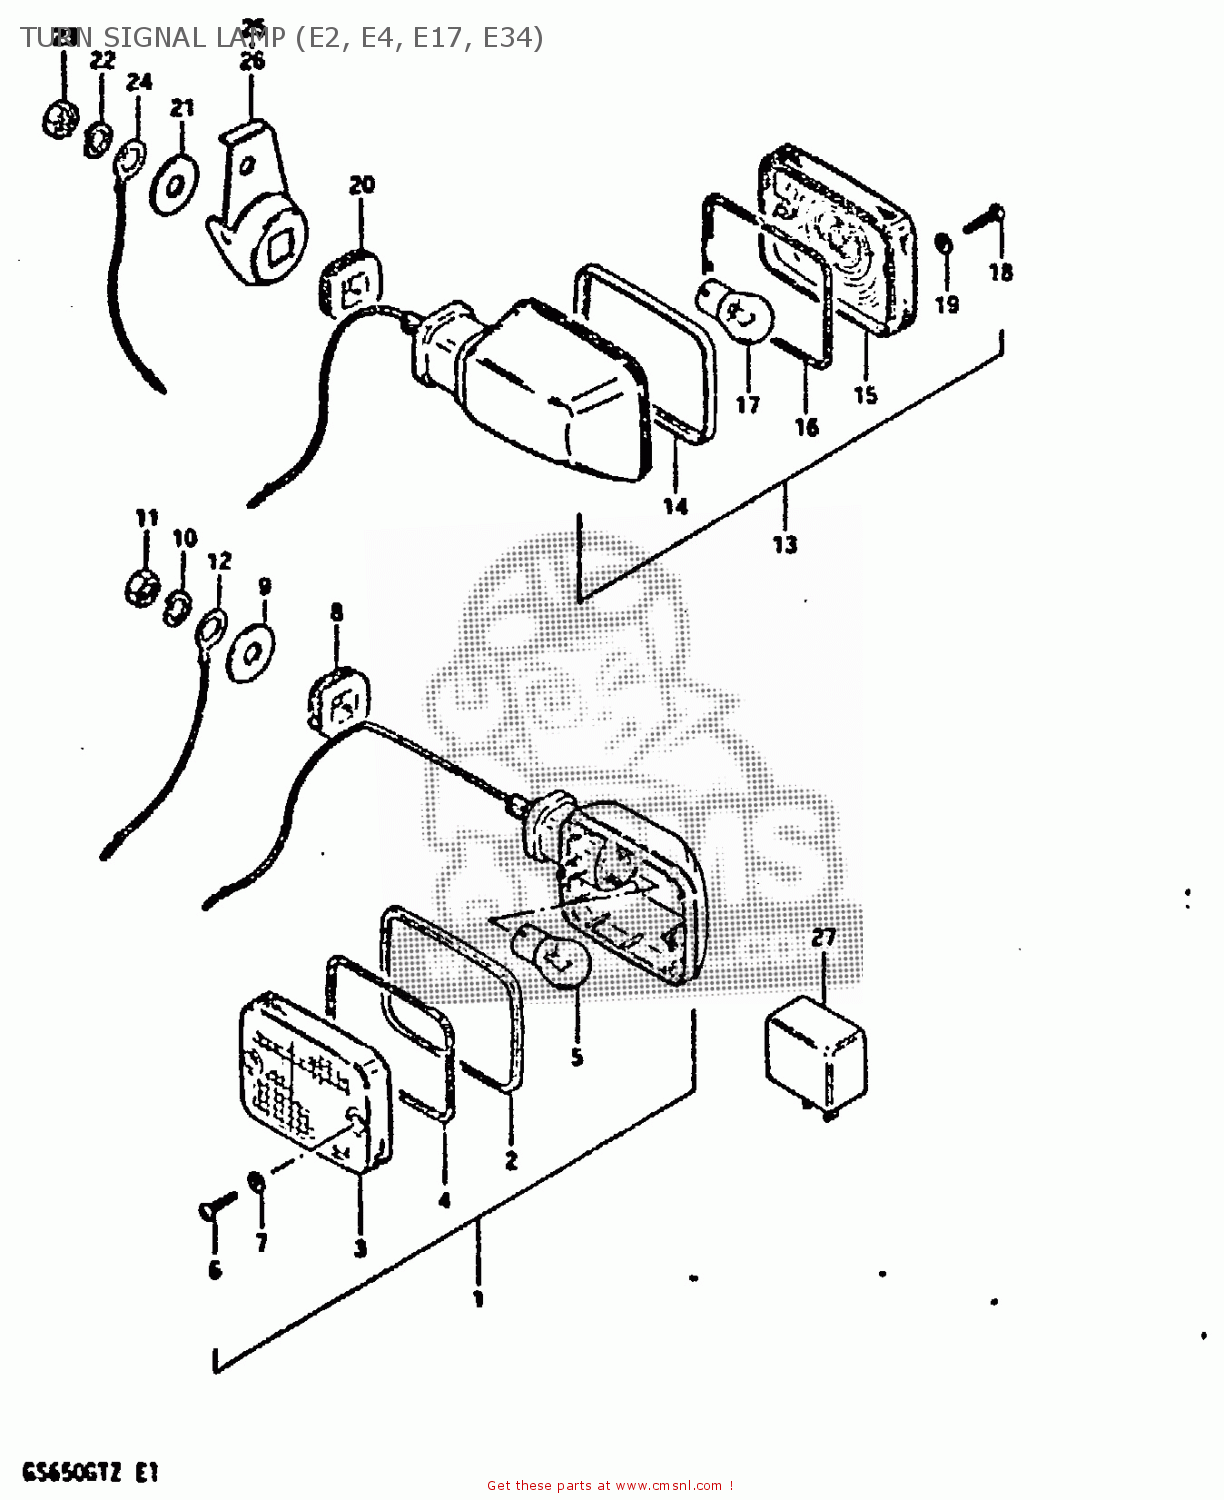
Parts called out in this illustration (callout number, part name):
1	LAMP ASSY,FR T
2	RIM
3	LENS
4	GASKET (NAS)
5	BULB 12V 21W
6	SCREW
7	GASKET (NAS)
8	CUSHION
9	WASHER (10.5X30X2.3)
10	LOCK WASHER
11	NUT
12	WIRE
13	LAMP, REAR TURN SIGNAL
14	RIM
15	LENS
16	GASKET (NAS)
17	BULB 12V 21W
18	SCREW
19	GASKET (NAS)
20	CUSHION
21	WASHER (10.5X30X2.3)
22	LOCK WASHER
23	NUT
24	LEAD WIRE,EARTH
25	BRACKET,REAR TURN SIGNAL
26	BRACKET,REAR TURN SIGNAL
27	RELAY,TURN SIGNAL
